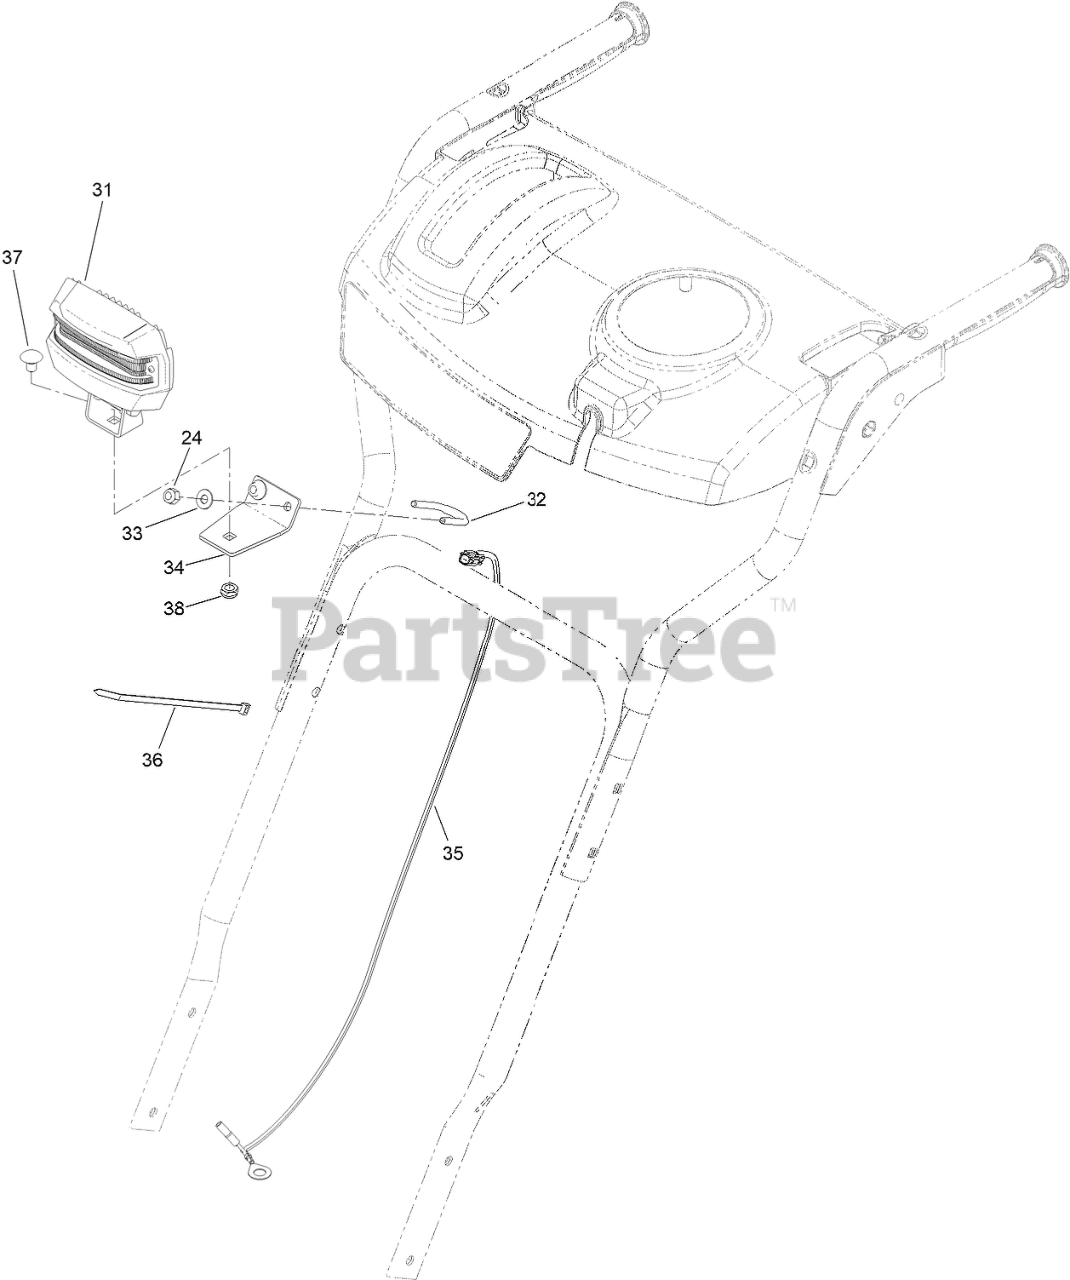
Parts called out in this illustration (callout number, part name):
24	NUT-HEX
31	LED LIGHT ASM
32	CLAMP-LIGHT
33	WASHER-PLAIN
34	BRACKET-LIGHT
35	HARNESS-WIRE
36	TIE-CABLE
37	BOLT-CARR
38	NUT-HEX
